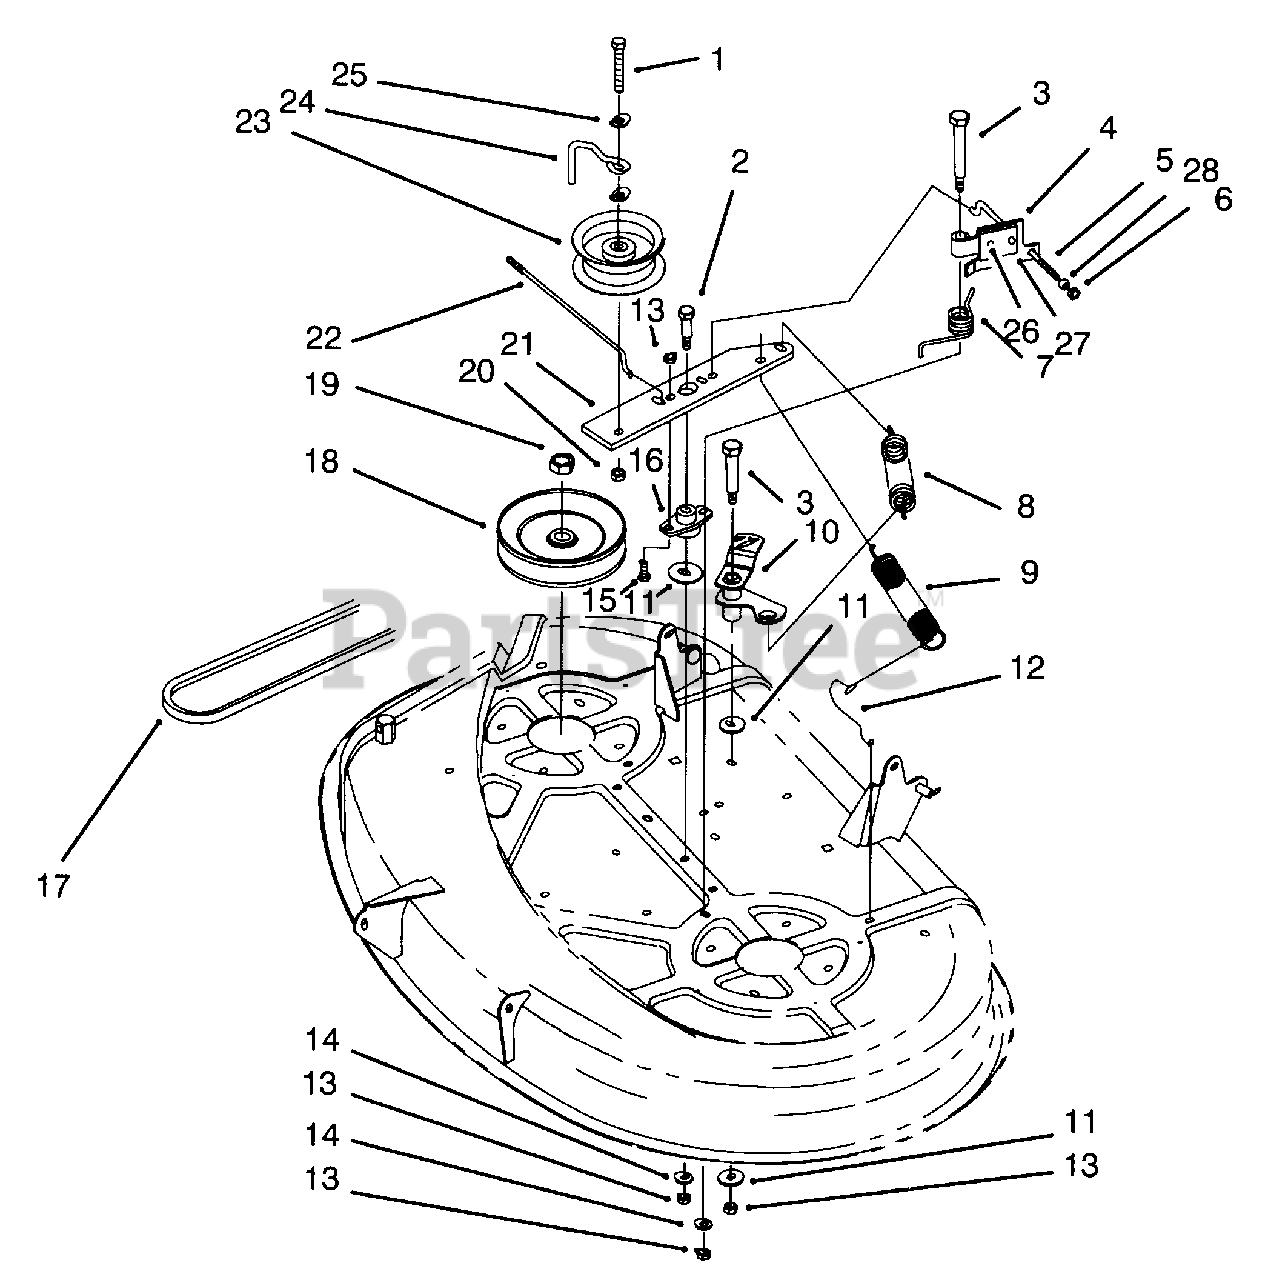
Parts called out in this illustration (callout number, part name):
1	Screw-Hex Hd. Cap
2	Bolt-Shoulder
3	Bolt-Shoulder
4	Brake-Deck (Incl. Ref. #26 & 27)
5	Rod-Deck Brake L.H.
6	Nut-Lock
7	Spring-Torsion
8	Spring-Deck Engage
9	Spring-Extension
10	Bellcrank
11	Washer-Fender
12	Hook-Spring Return
13	Nut-Lock
14	Washer-Flat
15	Screw-Hex Hd. Cap
16	Bushing-IdlerArm
17	V-Belt-Deck
18	Pulley-Deck
19	Nut-Lock
20	Nut-Lock
21	Arm-Idler
22	Rod-Deck Brake R.H.
23	Pulley-Idler
24	Guide-Idler Belt
25	Washer-Flat
26	Rivet-Pop
27	Pad-Brake
28	Ball-Swivel
